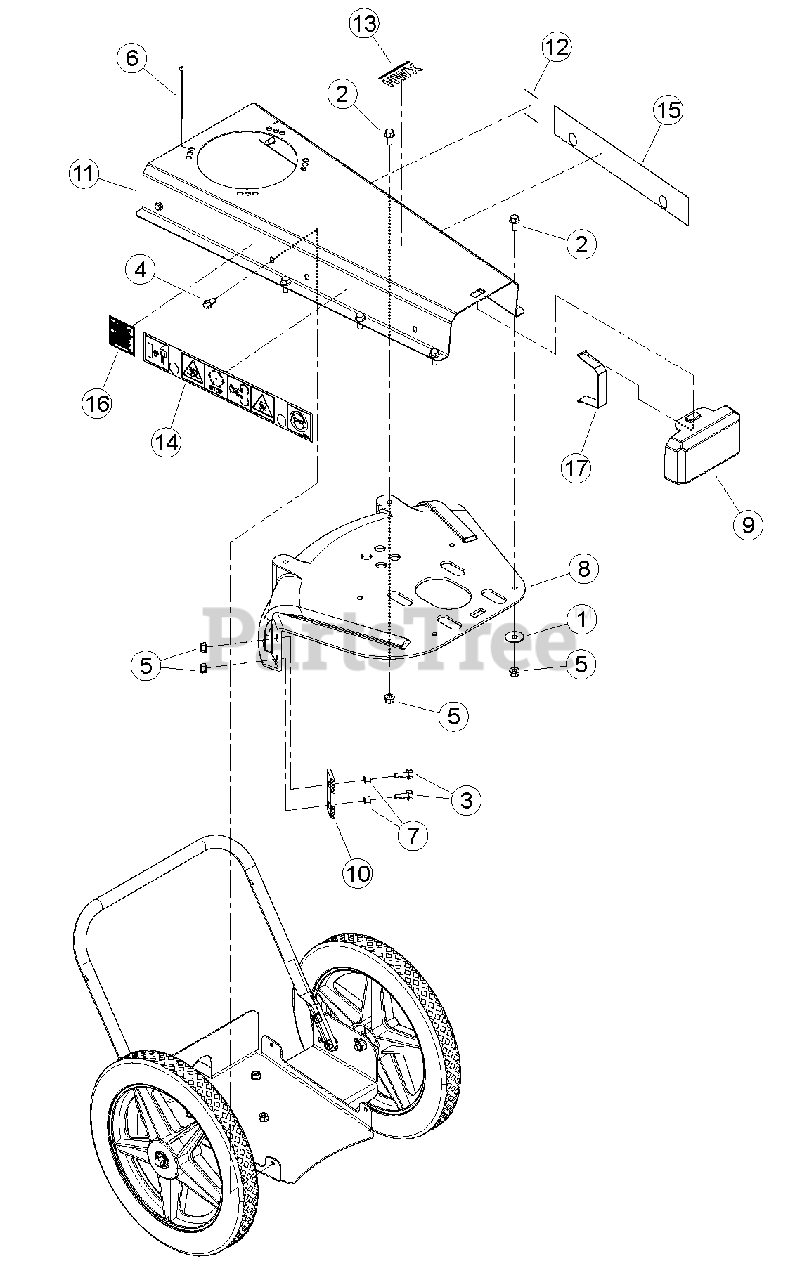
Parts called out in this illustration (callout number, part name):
1	WASHER, 5/16" FENDER ZP
2	BOLT, 5/16 X 3/4 FLANGE NC
3	BOLT, 5/16 X 7/8 FLANGE NC
4	SCREW, 11/32-12 X 7/8 FLANGE T-AB
5	NUT, 5/16-18 NYLOCK FLANGE
6	STRAP, 4 IN BLACK
7	SPACER, PLASTIC TRIMMER SHIELD
8	SHIELD, TRIMMER
9	COVER, PLASTIC TRIMMER FRONT
10	KNIFE, RECTANGULAR SHREDDING
11	ASSEMBLY, HWX BODY WITH DECALS
12	DECAL, ECHO BEARCAT QR CODE
13	DECAL, HWX PUSH TRIMMER
14	DECAL, HW SAFETY INFORMATION
15	DECAL, HW MAINTENANCE INFORMATION
16	DECAL, SPARK ARRESTOR
17	SPRING, CLIP HW TRIMMERS
